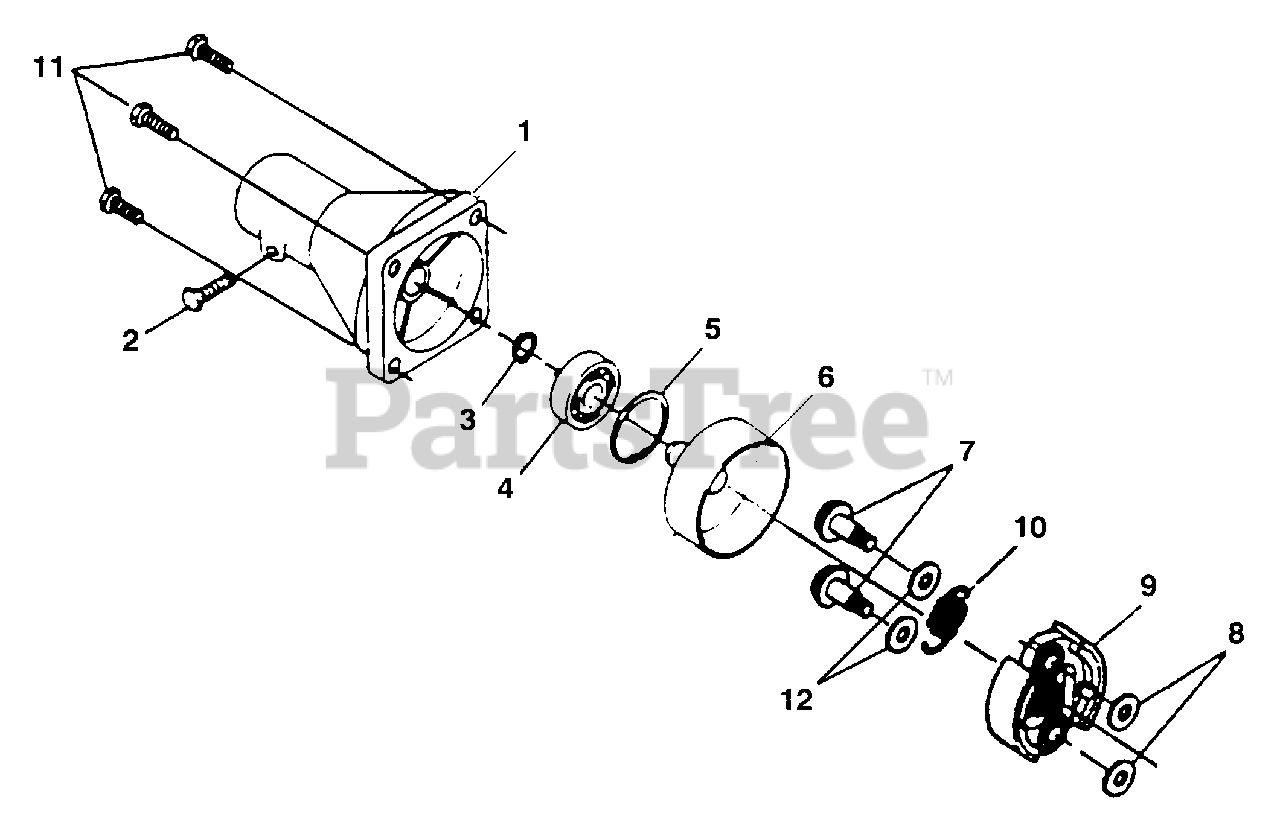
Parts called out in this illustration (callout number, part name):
1	CLUTCH CASE ASSY
2	BOLT & WASHER
3	SNAP RING
4	BALL BEARING
5	SNAP RING
6	CLUTCH DRUM
7	BOLT, CLUTCH
8	WASHER, CLUTCH
9	CLUTCH ASSY
10	SPRING, CLUTCH
11	BOLT & WASHER
12	WASHER, Clutch Bolt
